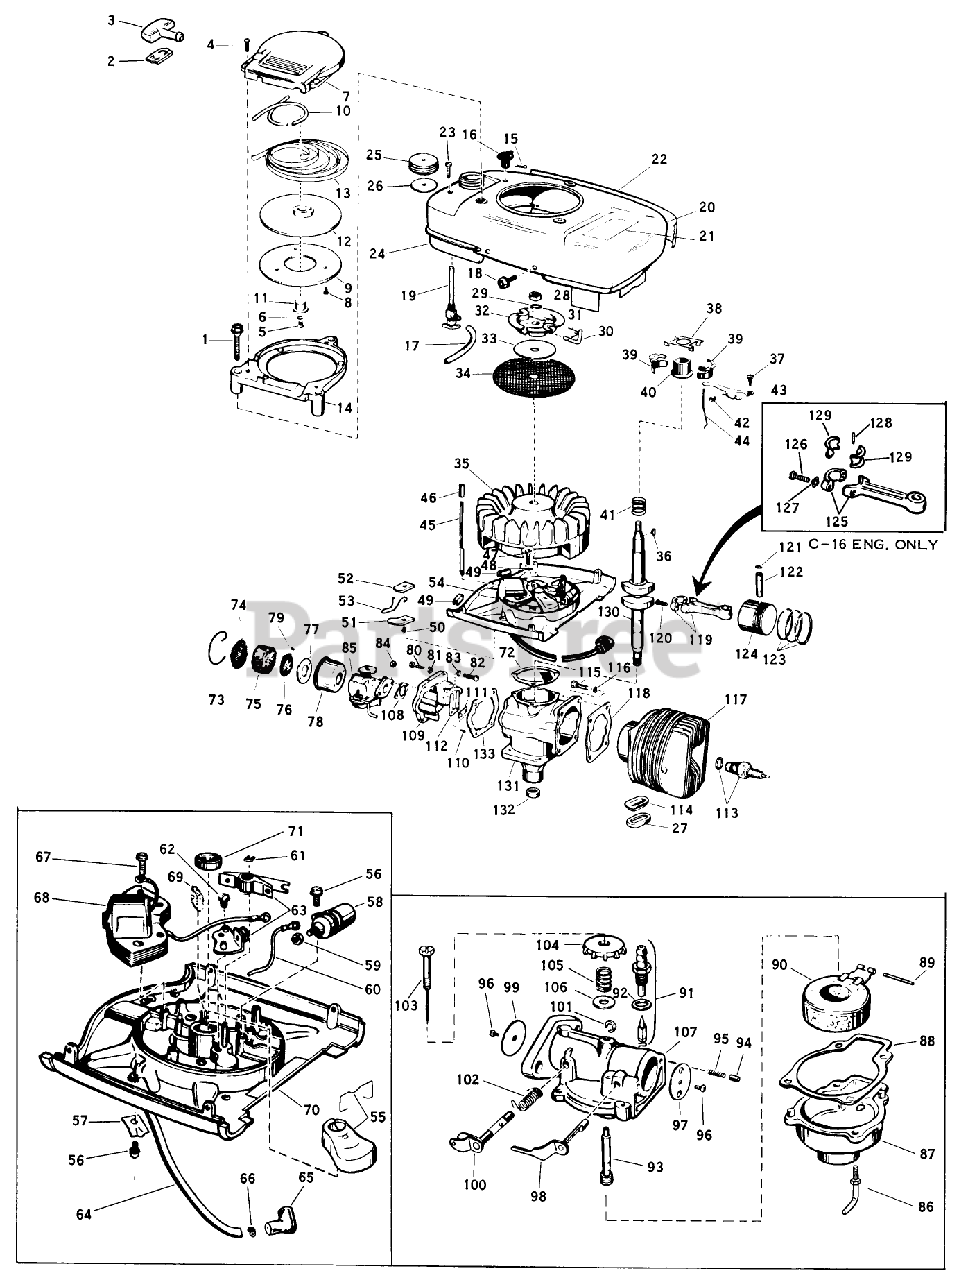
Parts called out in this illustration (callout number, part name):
9	Plate-Pulley
13	RECOIL SPRING
15	Cotter Pin-Choke Knob
16	KNOB, CHOKE BAR
18	SCREW S
19	VALVE&SCREEN SM
22	Decal-"Lawn-Boy"
25	Gas Cap
30	PIN - STARTER
40	COLLAR S
42	WEAR BLOCK S
43	GOVERNER LEVER AY
44	GOVERNOR ROD S
50	Screw Shut-off Switch
63	BREAKER AY. S
65	Cover-Rubber
72	GASKET S
75	ELEMENT
77	BACK-UP PLATE
80	SCREW S
84	STOP NUT
96	Screw-Choke Disc
98	CHOKE SHAFT&LVR AY
103	NEEDLE AY. S
105	Spring-Ndl. Adj.
108	GASKET S
111	PLATE-BACKUP, REED
113	Spark Plug
120	Screw-Connecting Rod
126	SCREW
129	LINER ASM
130	Crankshaft
133	GASKET
